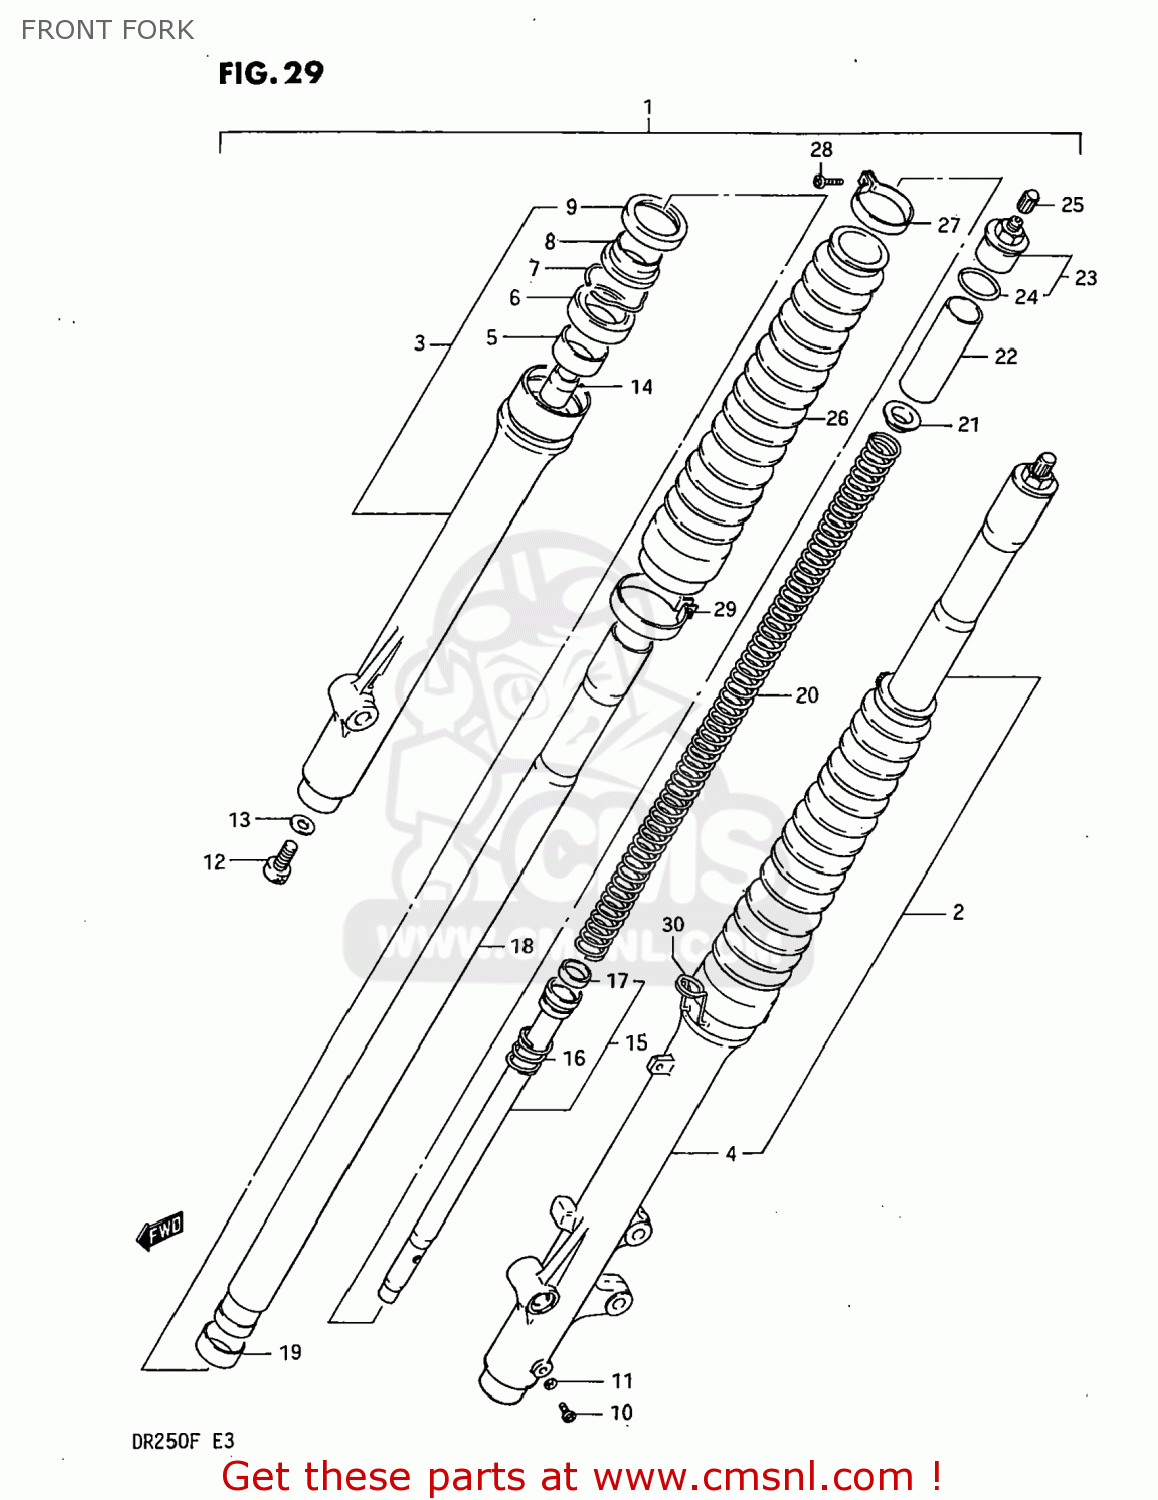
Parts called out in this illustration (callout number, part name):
1	DAMPER ASSEMBLY,RIGHT
2	DAMPER ASSEMBLY,LEFT
3	TUBE,FORK,OUTER,RIGHT
4	TUBE,FORK,LEFT,OUTER
5	METAL,FRONT FORK SLIDE
6	OIL SEAL,FRONT FORK
7	8
8	SEAL,DUST
9	CASE,DUST SEAL
10	SCREW
11	GASKET,DRAIN,PLUG (NAS)
12	BOLT,FORK CYLINDER(10X25)
13	GASKET (NAS)
14	PIECE,OIL LOCK
15	CYLINDER,FRONT FORK
16	SPRING
17	RING,FRONT FORK PISTON
18	TUBE,FORK,INNER
19	PISTON
20	SPRING,FRONT FORK
21	GUIDE,FRONT FORK SPRING C
22	COLLAR,SPRING
23	CAP,FR FORK INNER TUBE
24	O RING
25	CAP
26	BOOT,FRONT FORK COVER
27	BAND,BOOT
28	SCREW
29	BAND,FRONT FORK COVER
30	BAND,FRONT FORK COVER
